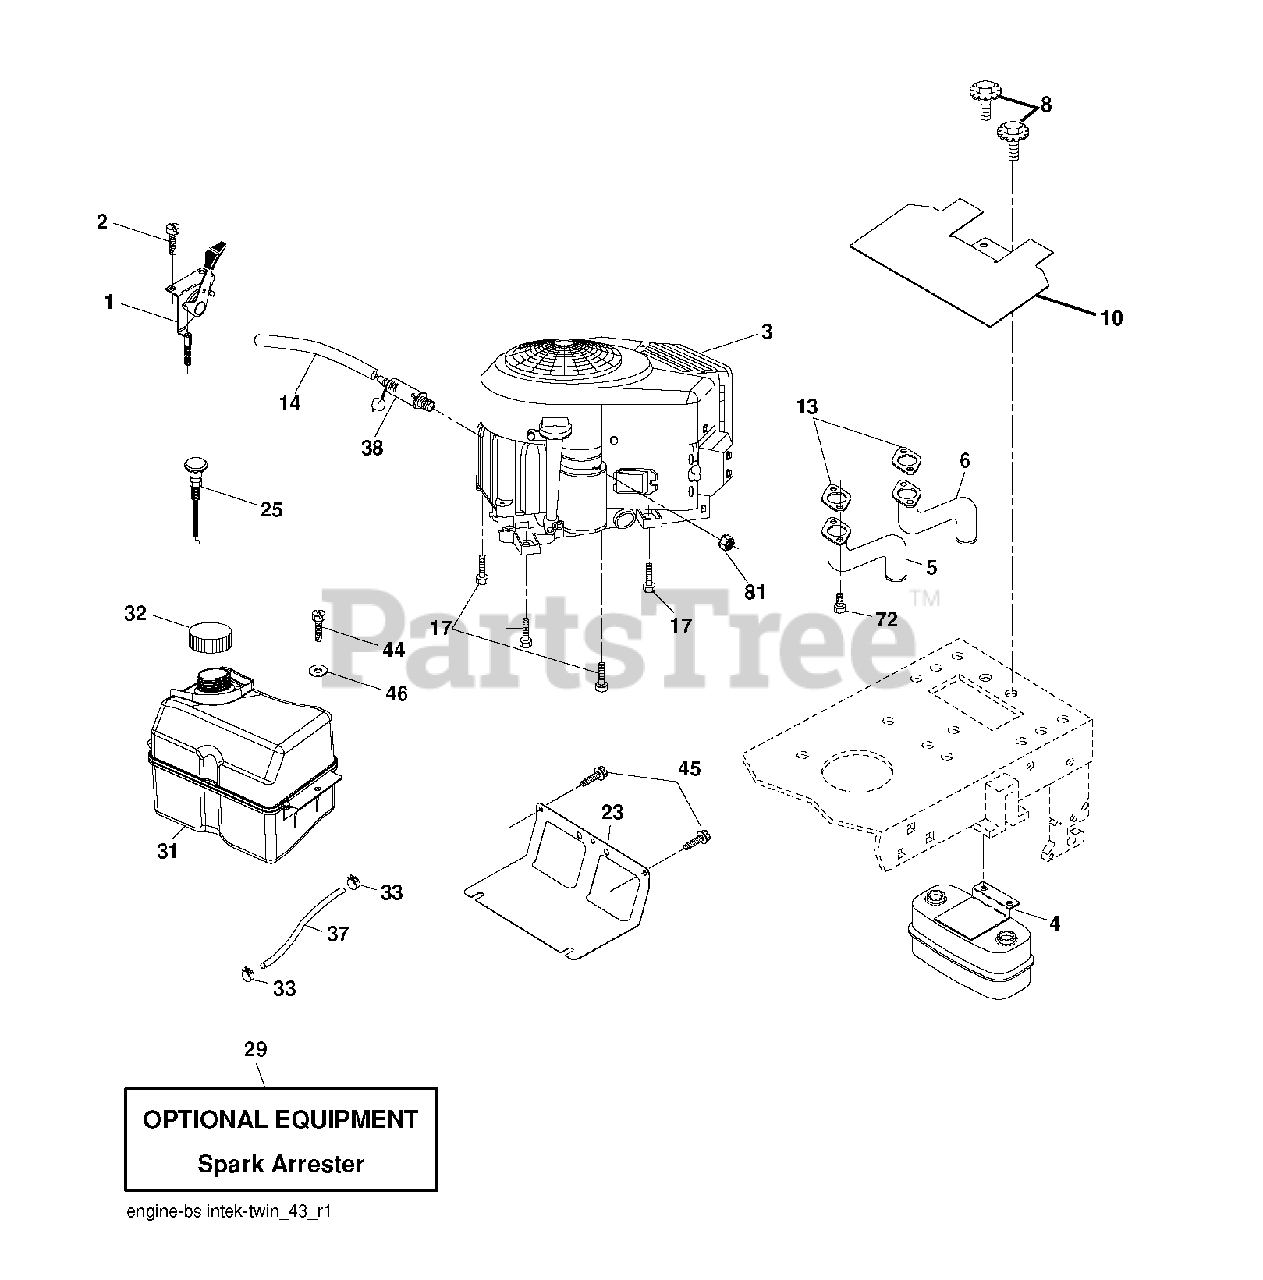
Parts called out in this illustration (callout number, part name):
1	THROTTLE CABLE
2	SCREW
4	MUFFLER.TWIN.CYL.LOW.TONE
5	EXHAUST TUBE RH
6	TUBE MANIFOLD LH
8	BOLT, 5/16-18 X 1 3/4
10	RP SHIELD HEAT MUFFLER
13	GASKET.MUFFLER
14	TUBE, DRAIN OIL ASM.
17	SCREW.3/8-16
23	SHEILD.BROWNING.DBR.GUARD
25	CONTROL CHOKE
29	ARRESTER SPARK (OPTIONAL)
31	TANK FUEL
32	FUEL CAP
33	HOSE CLAMP
37	LINE.FUEL.20
38	PLUG DRAIN OIL EASY
44	SCREW HEXWSHR 1/4-20X3/4
45	SCREW, 3/8-16X3/4
72	SCREW.SOCKET.HEAD.5/16-18
81	NUT
